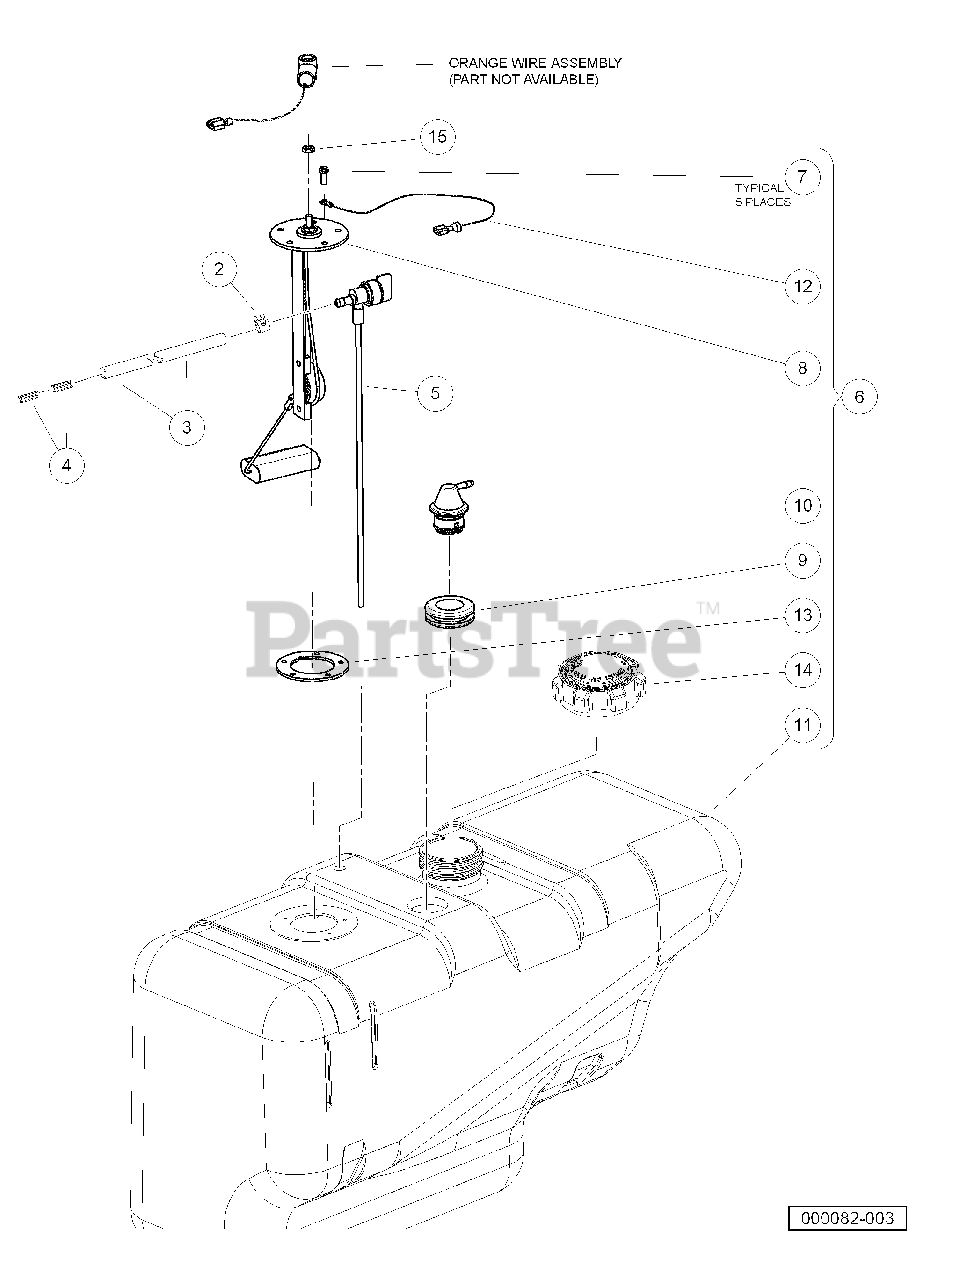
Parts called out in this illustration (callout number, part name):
1	Tank Kit w/Sending Unit
2	Clamp, 0.301 ID Hose
3	Fuel Line
5	Fuel Pickup w/Shut-Off Valve
6	Fuel Tank with Sending Unit
7	Screw, #10-16 Hex-Head Hi-Lo
8	Sending Unit, Fuel Level
9	Insulation Grommet
10	Vent, Fuel Tank
11	Fuel Tank with Vent and Sending Unit Hole
12	Wire Assembly #16 Black
13	Gasket, Rubber
14	Cap, Fuel Tank, Gasoline
15	Nut, #10-32 Brass Hex
